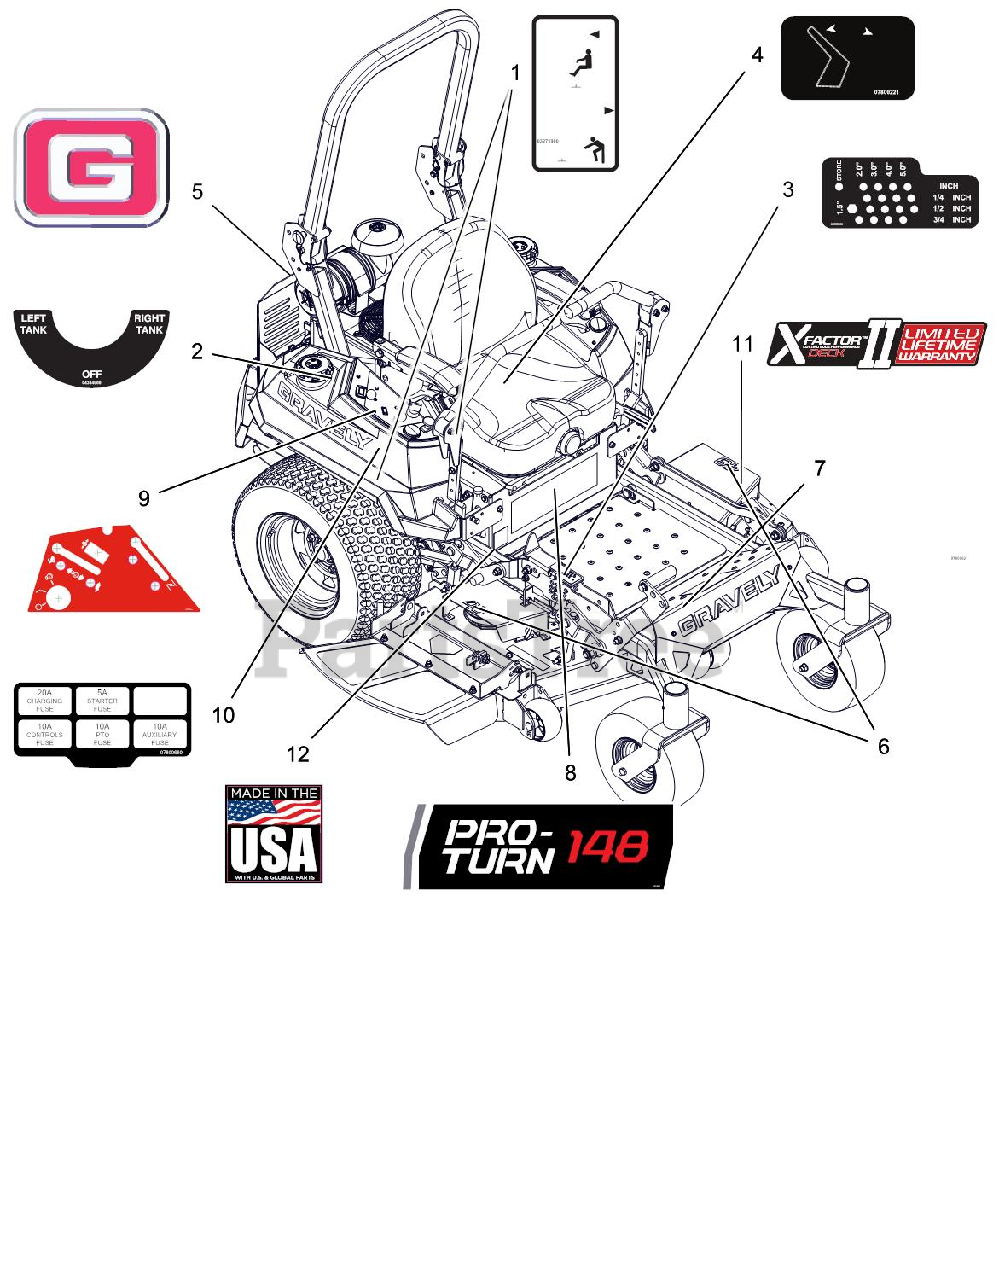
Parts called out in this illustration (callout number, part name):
1	DECAL, TRANSMISSION DISCONNECT
2	DECAL, FUEL VALVE
3	DECAL, HEIGHT OF CUT
4	DECAL, SEAT RELEASE
5	DECAL, GRAVELY BRAND
6	DECAL, 48
7	DECAL, BELT ROUTE RH V-SIDE IDLER
8	DECAL, PRO-TURN 148
9	DECAL, NON-EFI CONTROL PANEL
10	DECAL, FUSE BLOCK
11	DECAL, X-FACTOR DECK
12	DECAL, MADE IN USA
